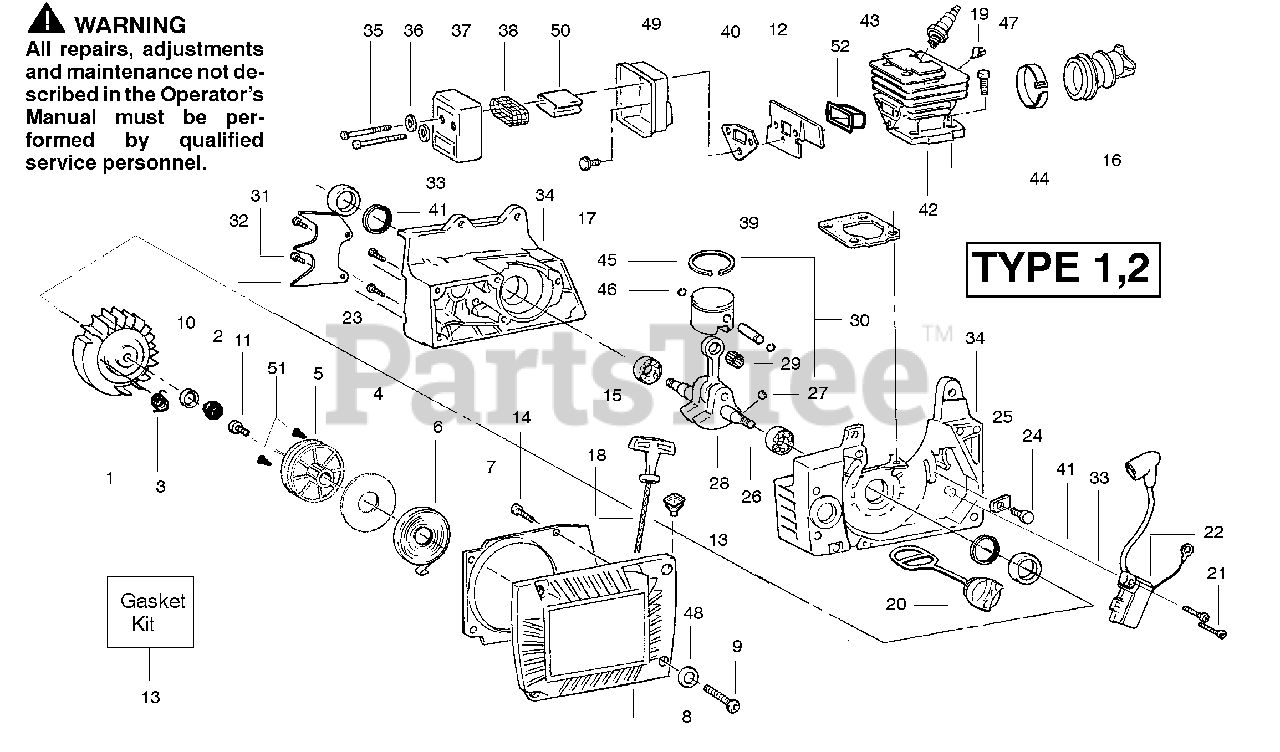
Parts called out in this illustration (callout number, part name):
1	Flywheel Ass'y. Kit
2	Nut-Flywheel
3	Spring-Starter Dog
5	Starter Pulley
6	Starter Spring
7	Baffle Plate
8	Fan Housing Ass'y.
10	Washer-Conical
12	Muffler Back Plate
13	Kit - Gasket
15	Starter Handle
16	Boot-Intake
18	Rope Kit
20	Oil Cap Ass'y.
21	Screw
22	Ignition Module
26	Crankshaft Bearing
27	Flywheel Key
28	Crankshaft & Rod Ass'y.
29	Piston Pin Bearing
30	Piston Kit
33	Crankshaft Seal
34	Crankcase Ass'y.
37	Muffler Cover
38	Spark Arrestor Screen
39	Gasket Kit
40	Muffler Gasket
41	Snap Ring
42	Cylinder Ass'y.
43	Spark Plug (RCJ-6Y)
44	Clamp Ass'y.
45	Piston Ring
46	Retainer
49	Muffler Body
50	Muffler Diffuser
52	Exh Port Insulatora
